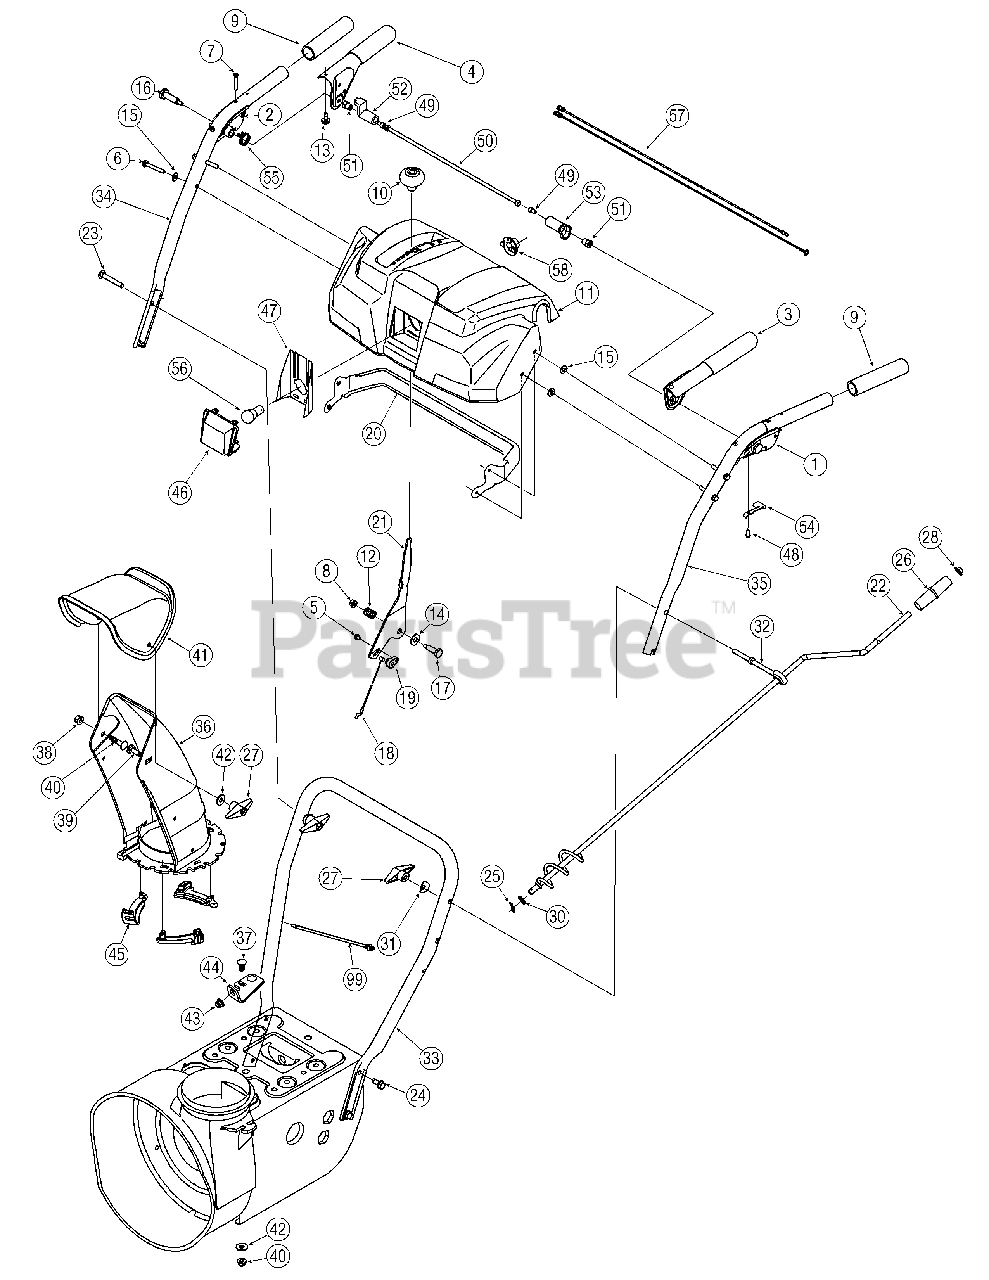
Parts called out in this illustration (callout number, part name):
1	Handle Assembly, Lock, LH
2	Handle Assembly, Lock, RH
3	Handle Ass’ y, Engagement LH
4	Handle Ass’y, Engagement,RH
5	Screw, #10-16, 0.500
6	Screw, 1/4-20, 1.750
7	Screw, Machine, #10-24, 1.375
8	Nut, Flange Lock, 1/4-20, Nylon
9	Grip, 1.0 ID x 5.0
10	Knob, Shift
11	Handle Panel, O-Style
12	Spring, .39 x .60 x .88
13	Bumper, Rubber, .62 OD x .22
14	Washer, Flat, .385 x .870
15	Washer, Flat, .25 x .630 x .0515
16	Screw, Shoulder, .43 x 1.34, 1/4-20
17	Screw, Shoulder, .374 Dia. X 1.05
18	Cable, Speed Selector
19	Barrel Holder, Cable, LH
23	Screw, Carriage, 5/16-18, 2.25
24	Screw, 5/16-18, 0.75, Gr5
25	Pin, Cotter, .072 x 1.13
26	Crank Knob, 1.0 Dia. x 3.2, Black
27	Knob Assembly, Wing Nut, 5/16-18
28	Cap, Push, 3/8 Rod
29	Grommet, .44 ID x .94 OD .50
30	Washer, Flat, .375 x .738 x .063
31	Washer, Saddle, 320 x .93 x.060
32	Eye Bolt, Chute Crank
36	Chute, Lower, 5.0 Diameter
37	Bolt, Carriage, 5/16-18, 1.0
38	Nut, Flange Lock, 5/16-18, Nylon
39	Bolt, Carriage, 5/16-18, 1.0
40	Bolt, Carriage, 5/16-18, .750
41	Chute, Upper, w/ Label
42	Washer.349 ID x .879 OD
43	Bushing, Plastic, .380
45	Flange Keeper, Chute
47	Reflector Label, Lens
48	Screw, #8-16 x 0.50
49	Screw, 1/4-20 x.375
50	Pivot Rod
51	Shoulder Nut, 1/4-20
52	Lock Plate
53	Clutch Lock Cam
54	Clutch Lock Spring
55	Torsion Spring
56	Lamp
57	Wire Harness
58	Light Socket
